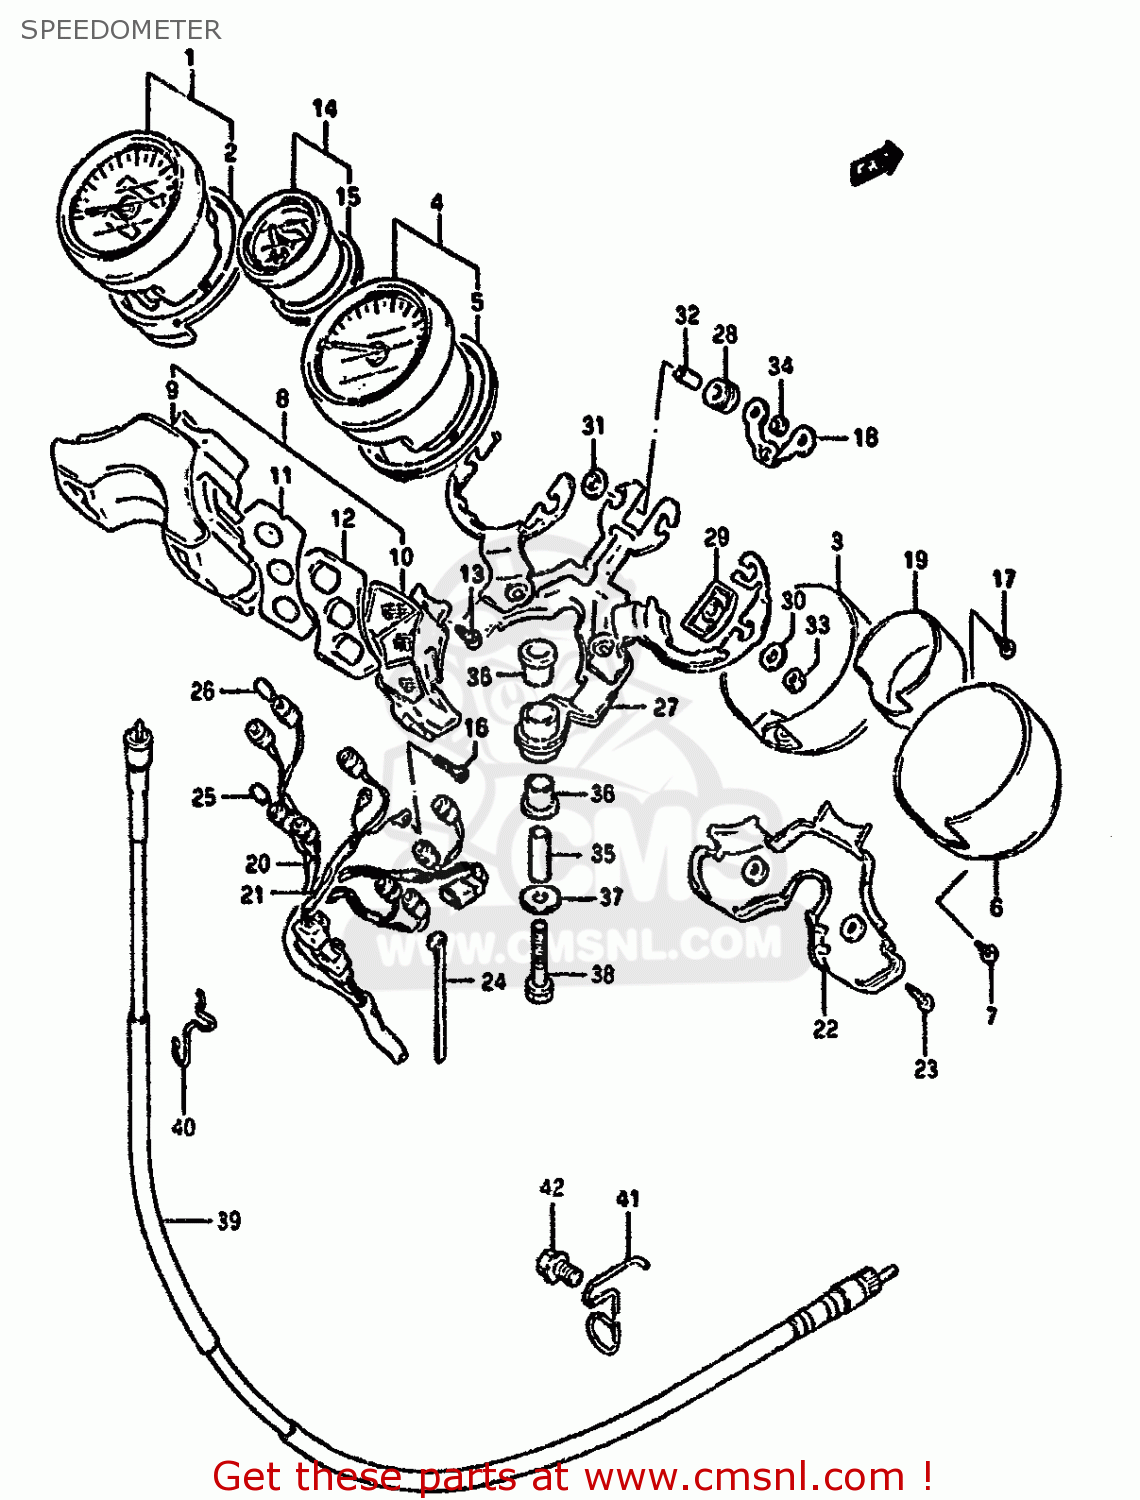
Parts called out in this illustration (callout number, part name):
1	SPEEDOMETER
2	DAMPER
3	COVER,SPEEDOMETER
4	TACHOMETER
5	DAMPER
6	TACHOMETER
7	SCREW
8	BOX
9	CASE,UPR
10	LWR CASE
11	PANEL
12	GASKET (NAS)
13	SCREW
14	FUEL METER
15	DAMPER
16	SCREW(3X22)
17	SCREW
18	PLATE,SET
19	COVER,FUEL METER
20	SOCKET,METER
21	SOCKET,FUEL METER
22	COVER,PILOT BOX
23	SCREW
24	CLAMP
25	BULB(12V3W,T6.5)
26	BULB(12V1.7W,T6.5)
27	BRACKET,METER
28	DAMPER
29	DAMPER
30	WASHER
31	WASHER,FUEL,METER
32	SPACER,FUEL METER
33	NUT
34	NUT
35	BUSHING L:34
36	CUSHION
37	WASHER (8.2X26X1.6)
38	BOLT
39	CABLE ASSY,SPEEDOMETER
40	GUIDE,SPEEDOMETER CABLE
41	CLAMP,SPEEDOMETER CABLE
42	BOLT(10X12)
